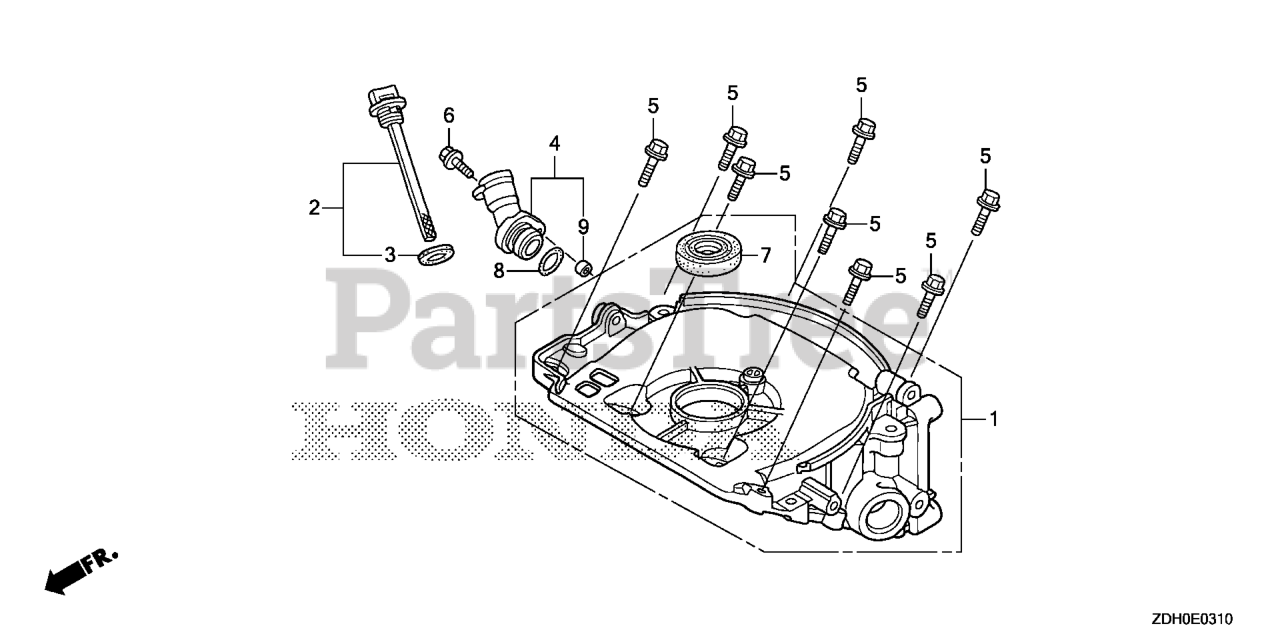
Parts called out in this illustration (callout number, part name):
1	CASE ASSY., OIL
2	CAP ASSY., OIL FILLER
3	GASKET, OIL FILLER CAP
4	EXTENSION, OIL FILLER
5	BOLT, FLANGE (5X23)
6	BOLT, FLANGE (5X14)
7	OIL SEAL (17X27X5) (KOYO)
8	O-RING (21.2X2.4) (ARAI)
9	COLLAR, TOP COVER
